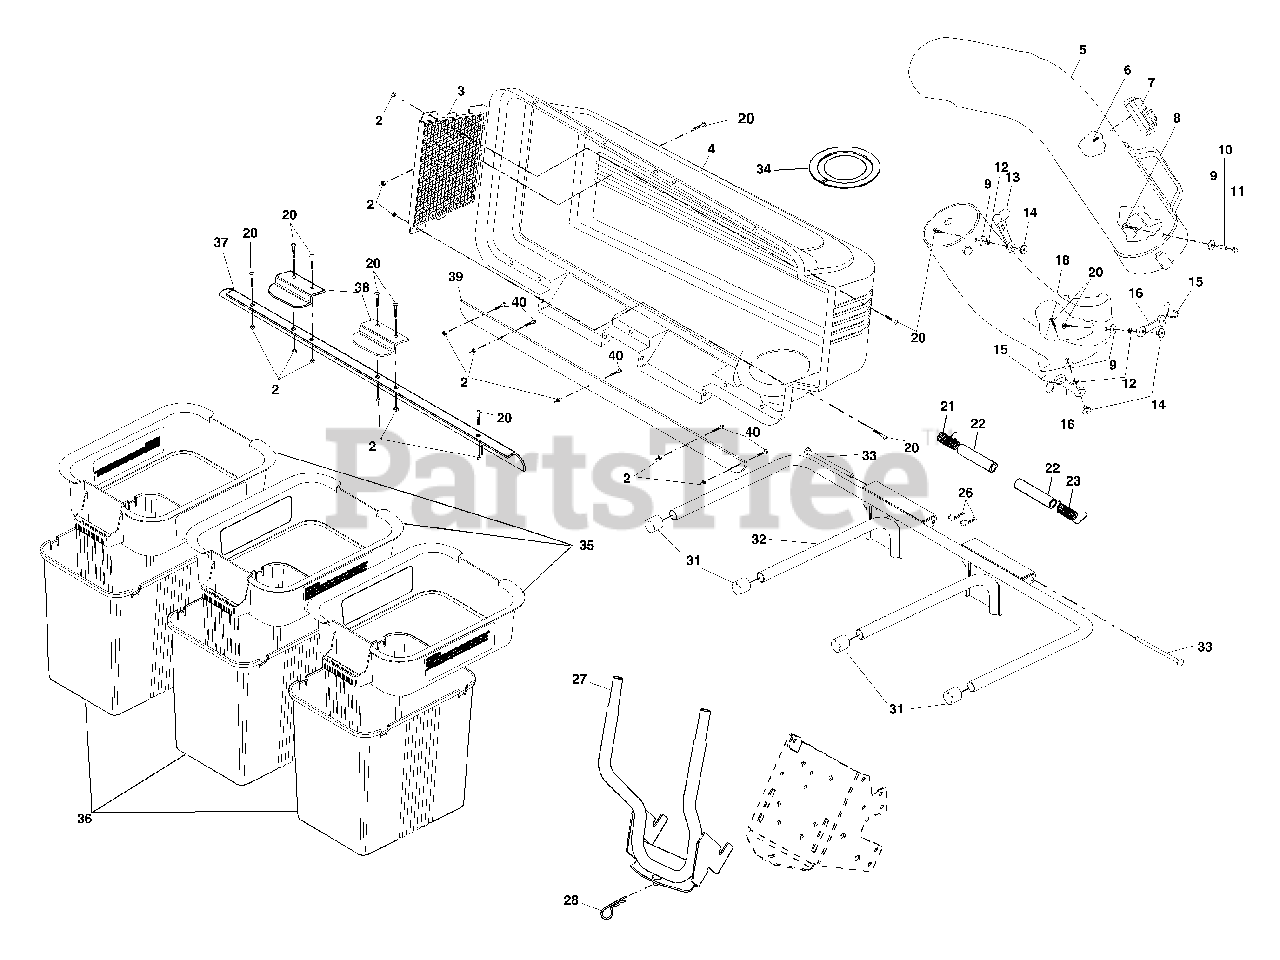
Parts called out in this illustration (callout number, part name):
2	Nut, Crownlock #10-24
3	Screen, Cover
4	Cover
5	Chute, Upper
6	Screw, Special #10-14x1/2
7	Dump bag Indicator
8	Screw, #10-24 x 1-1/8
9	Washer 3/16x3/4x16 Ga.
10	Spacer, Split
11	Nut, Acorn #10-24
12	Washer, lock
13	Latch, Chute
14	Nut, Weld
15	Latch, Hook
16	Rubber, Latch
18	Chute, Lower
20	Screw #10-24 x 5/8
21	Spring, Cover L.H. (black)
22	Spacer, Cover
23	Spring, Cover R.H. (gray)
26	Spring, Retainer
27	Support Assembly
28	Spring, Retainer
31	Plug, Tubing End
32	Bagger, Frame
33	Pin, Hinge
34	Gasket, Cover
35	Container, Top
36	Container, Bottom
37	Seal, Cover
38	Latch Handle, Cover
39	Strip, Reinforcement
40	Screw #10-24 x 1/2
